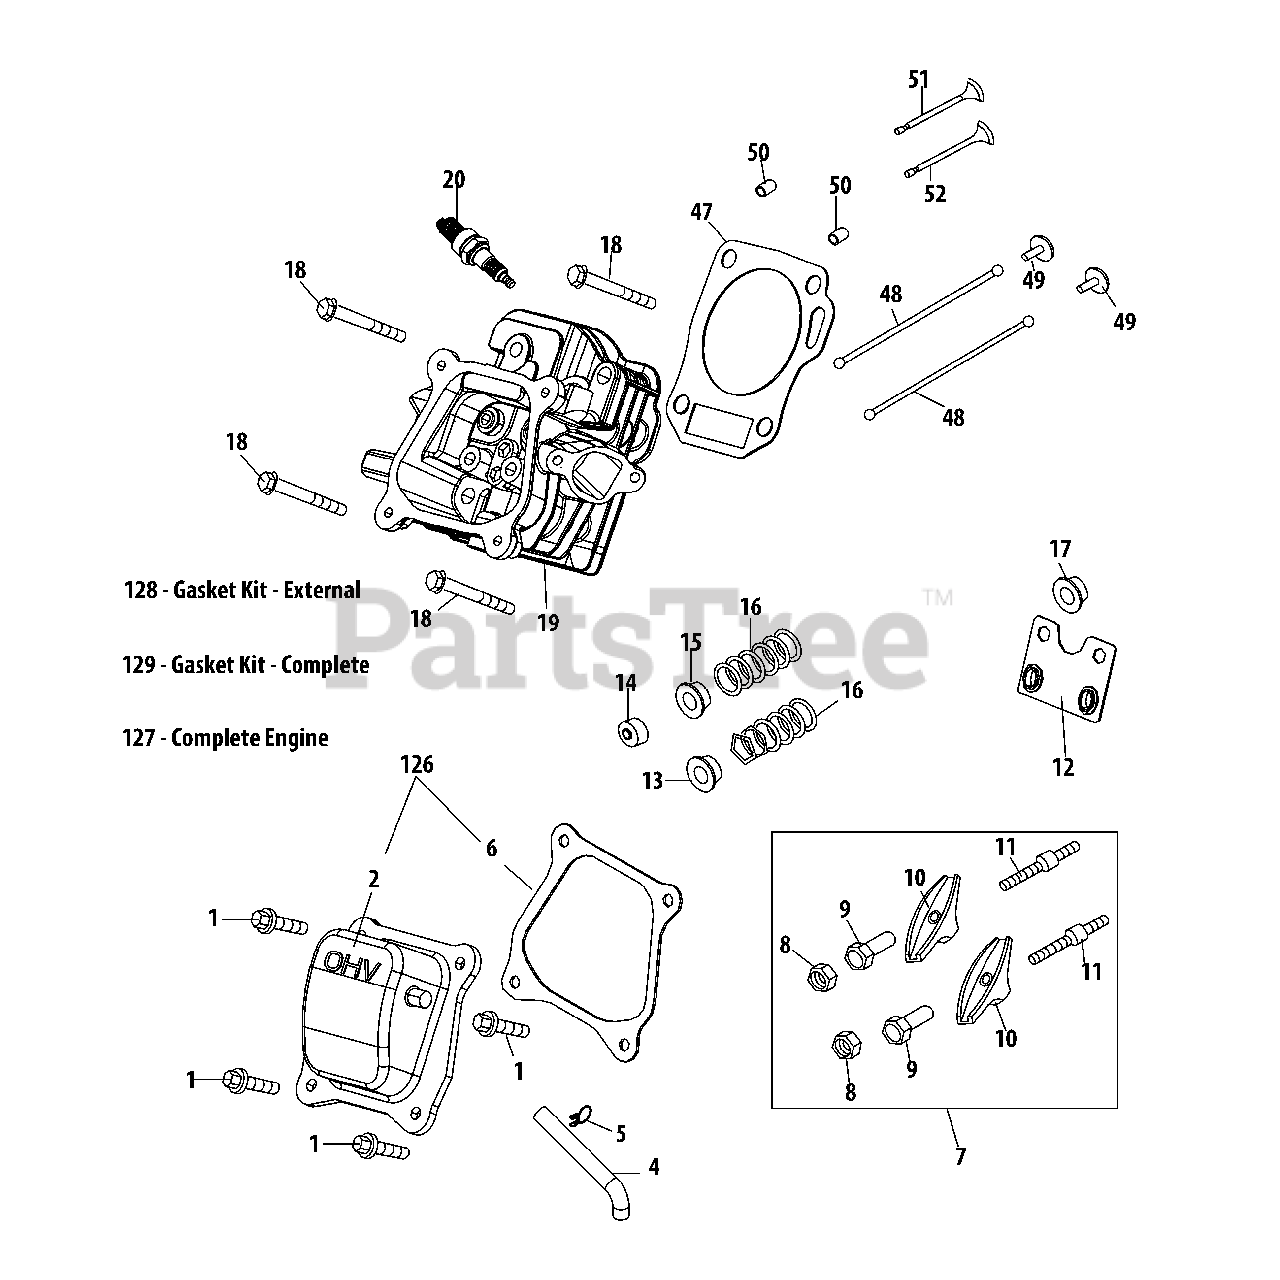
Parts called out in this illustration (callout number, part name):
1	Bolt M6×16
2	Valve Cover
4	Breather Hose
5	Breather Hose Clamp
6	Valve Cover Gasket
7	Rocker Arm Assembly
8	Nut, Pivot Locking
9	Adjusting Nut ,Valve
10	Rocker Arm
11	Bolt, Pivot
12	Push Rod Guide
13	Valve Spring Retainer (Intake)
14	Exhaust Valve Adjuster
15	Valve Spring Retainer (Exhaust)
16	Valve Spring
17	Valve Seal (Intake)
18	Bolt M8×55
19	Cylinder Head Assembly
20	Spark Plug/F6Rtc
47	Gasket, Cylinder Head
48	Push Rod Kit
50	Dowel Pin 10X16
51	Valve Kit
52	Valve Kit
126	Valve Cover Kit
127	Complete Engine
128	Gasket Kit - External
129	Gasket Kit - Complete
